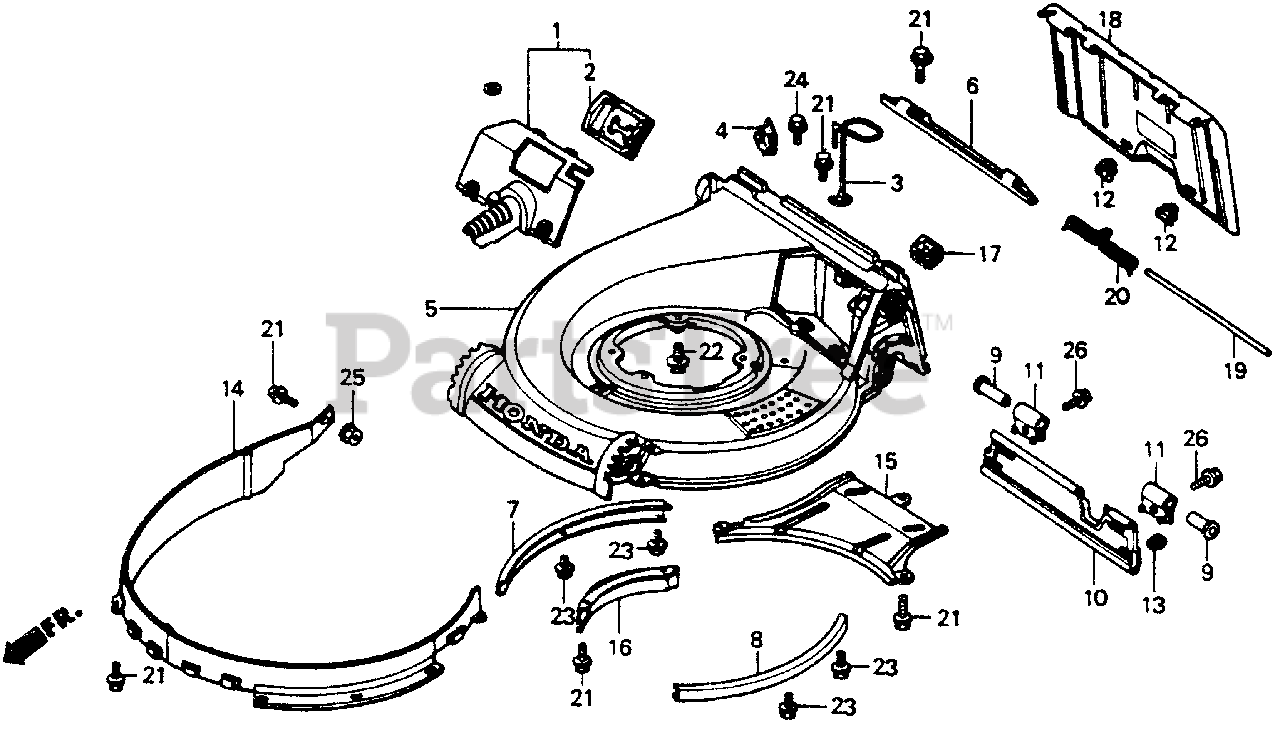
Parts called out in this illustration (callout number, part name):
1	COVER, DRIVESHAFT *NH192M* (GENTLY SILVER METALLIC) (NOT AVAILABLE)
2	GROMMET, COVER (NOT AVAILABLE)
3	GUIDE, CABLE
4	GROMMET D, CABLE
5	HOUSING, CUTTER *NH192M* (GENTLY SILVER METALLIC)
6	HINGE, DISCHARGE GUARD
7	GUARD, R. SAFETY (NOT AVAILABLE)
8	GUARD, L. SAFETY (NOT AVAILABLE)
9	BUSH, SAFETY SHIELD
10	SHIELD, SAFETY
11	HANGER, SAFETY SHIELD
12	STOPPER, DISCHARGE GUARD
13	STOPPER, DISCHARGE GUARD Use up to Frame SN 1186736.
14	LINER (INNER)
15	GUIDE, SCROLL
16	LID, ROTO-STOP COVER (NOT AVAILABLE)
17	GROMMET C, CABLE
18	GUARD, DISCHARGE
19	SHAFT, HINGE (NOT AVAILABLE)
20	SPRING, GUARD RETURN
21	BOLT, FLANGE (6X12) (CT200)
22	BOLT, ENGINE SETTING
23	BOLT, FLANGE (6X10)
24	BOLT, FLANGE (6X25)
25	NUT, FLANGE (6MM)
26	BOLT, FLANGE (6X12) Use up to Engine SN 1543277.
